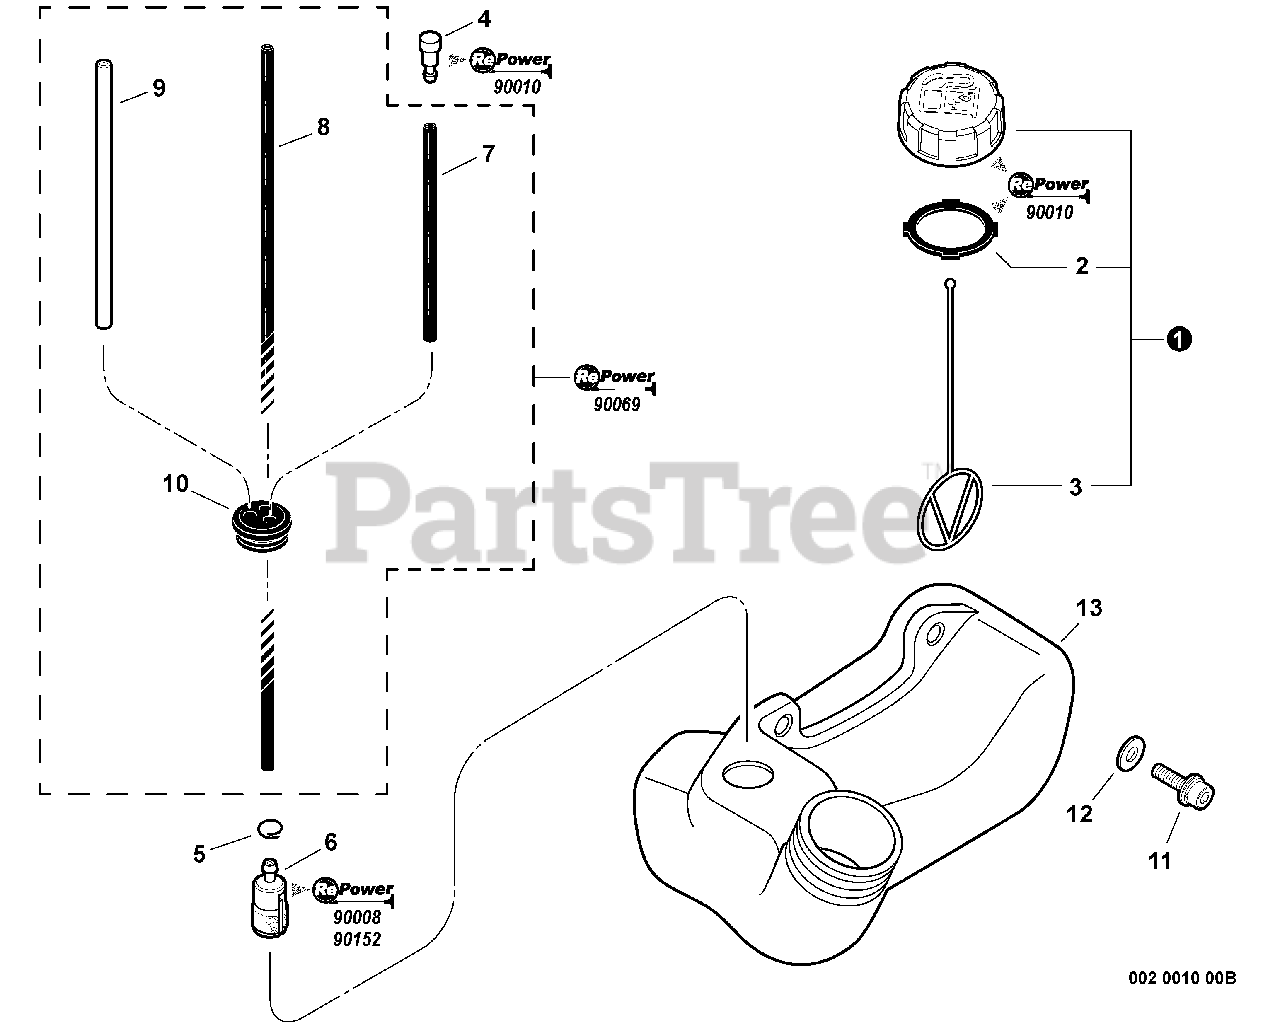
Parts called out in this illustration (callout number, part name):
1	CAP ASSY, FUEL
2	GASKET, FUEL CAP
3	CONNECTOR, CAP L= 100 MM
4	VENT ASSY
5	CLIP 6 MM
6	FILTER, FUEL
7	PIPE, FUEL 3x-5x-70 BLACK
8	PIPE, FUEL 3x-5x-180
9	PIPE, FUEL 3×6×80 CLEAR
10	GROMMET, FUEL
11	BOLT 5×20
12	WASHER 5.5×12×0.8
13	TANK, FUEL
14	FILTER KIT - REPOWER
15	CAP/VENT KIT - REPOWER
16	BULK PIPE - 3×5 MM BLACK (4 PIECES×2 M)
17	BULK PIPE - 3×6 MM CLEAR (4 PIECES×2 M)
18	FUEL SYSTEM KIT
19	TUNE-UP KIT - REPOWER
